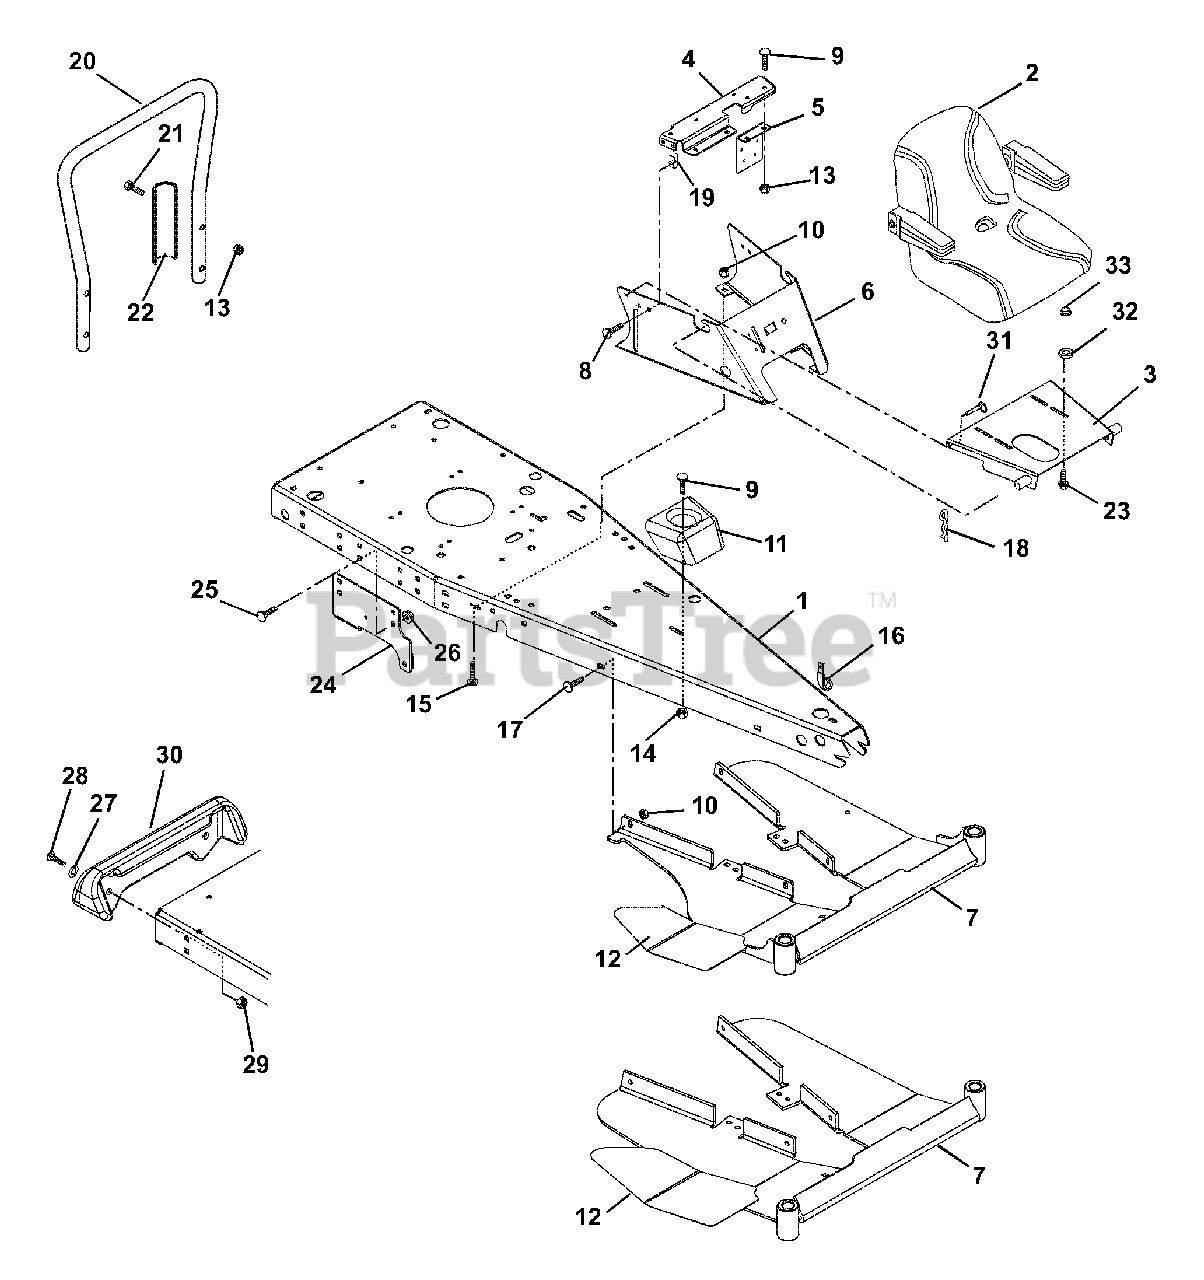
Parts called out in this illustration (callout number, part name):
2	Seat, TS2500 Michigan with Arms
3	Weldment, Seat Plate
4	Reforcement, Seat Support
5	Panel, Solenoid Mounting
6	Seat Support
7	Weldment, Footrest (060)
7	Weldment, Footrest (062)
8	Bolt-Serrated Hex Flange Washer Head .25-20 x .75
9	Bolt, Round Head Square Neck .31-18 x .75 Grade 5
10	Nut, Locking Top Flange .38-16
11	Cupholder
12	Grip, Footrest Left Hand (060)
12	Grip, Footrest Left Hand (062)
12	Grip, Footrest Right Hand (060)
12	Grip, Footrest Right Hand (062)
13	Nut-Locking-Top-Flange .31-18
14	Nut-Spin Lock-Flange .312-18
15	Bolt-Round Head Square Neck .38-16 x .75 Grade 5
16	J-Clamp
17	Bolt-Round Head Square Neck .38-16 x 1.00 Grade 5
18	Pin-Hair-External .12 x .31 x 2.37
19	Nut-Retainer .25-20 x .56
20	Tube (060, 062)
21	Bolt, Hex .31-18 x 1.50 Grade 5 (060, 062)
22	Brace (060, 062)
23	Bolt-Serrated Hex Flange Washer Head .31-18 x 1
24	Bracket, Transmission - Right Hand
24	Bracket, Transmission - Left Hand
25	Bolt, Round Head Square Neck .38-16 x .75 Grade 5
26	Nut, Locking Top Flange .38-16
27	Washer-Flat-Steel .438 x 1.00 x .083
28	Bolt-Hex .38-16 x 1.75 Grade 5
29	Nut-Locking-Top-Flange .38-16
30	Weight
31	Pin, Detent with Ring .25 x 1.00
33	Nut, Push .312
